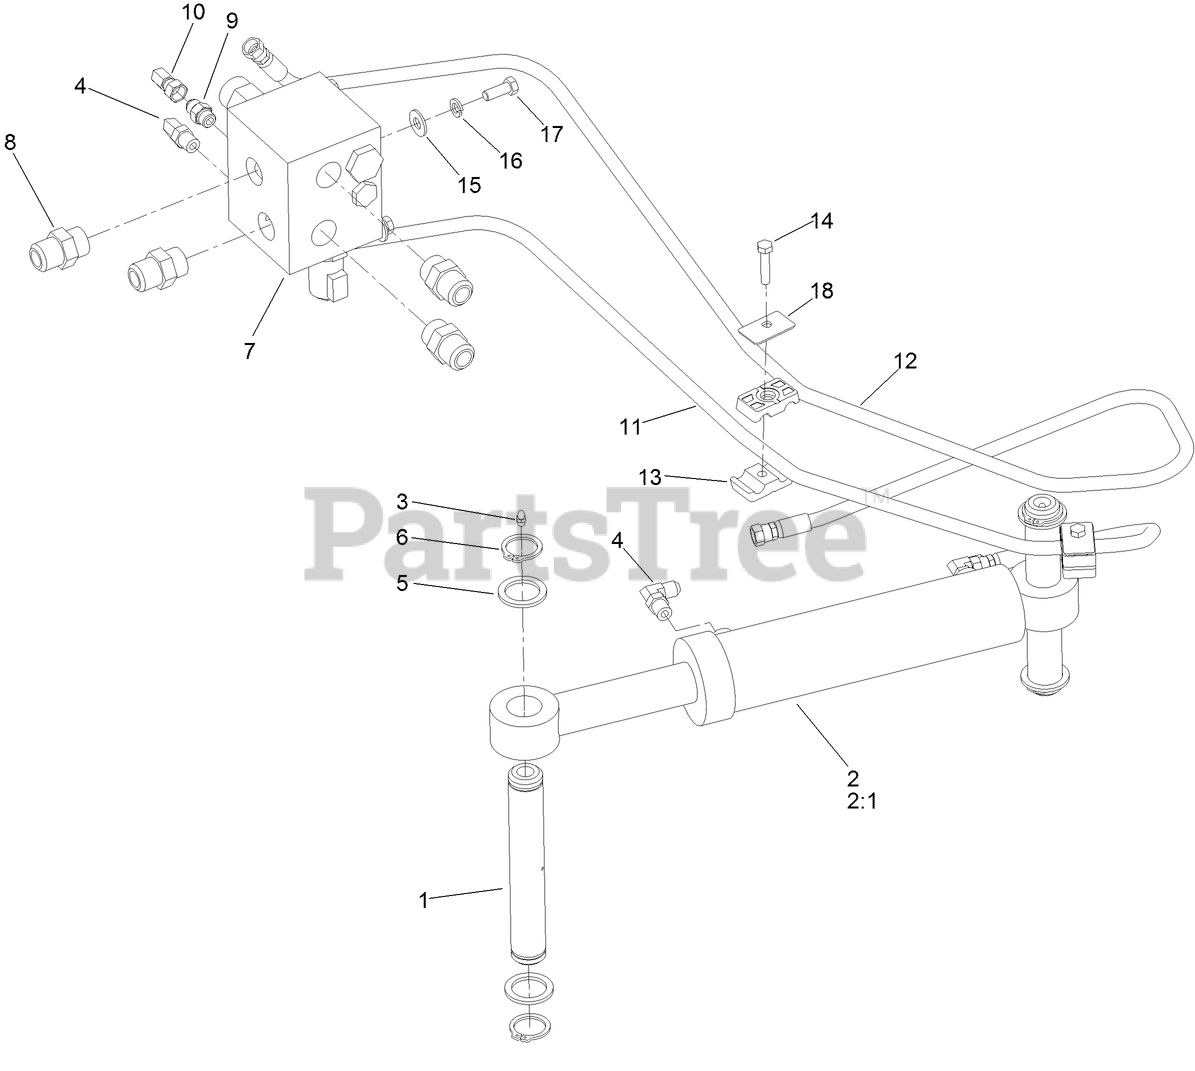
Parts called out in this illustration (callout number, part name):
1	PIN-PIVOT
2	HYDRAULIC CYLINDER ASM
3	FITTING-ZERK
4	FITTING-ELBOW
5	WASHER-STEERING
6	RING-RETAINING, EXTERNAL
7	HYDRAULIC MANIFOLD ASM
8	FITTING-STRAIGHT
9	FITTING,STRAIGHT,6-MORB X 6-M37JIC
10	ELBOW-SWIVEL, 90 DEG
11	HYD HOSE ASM
12	HYD HOSE ASM
13	CLAMP-TUBE
14	SCREW-HH
15	WASHER-FLAT
16	WASHER-LOCK
17	SCREW-HH
18	COVERPLATE
